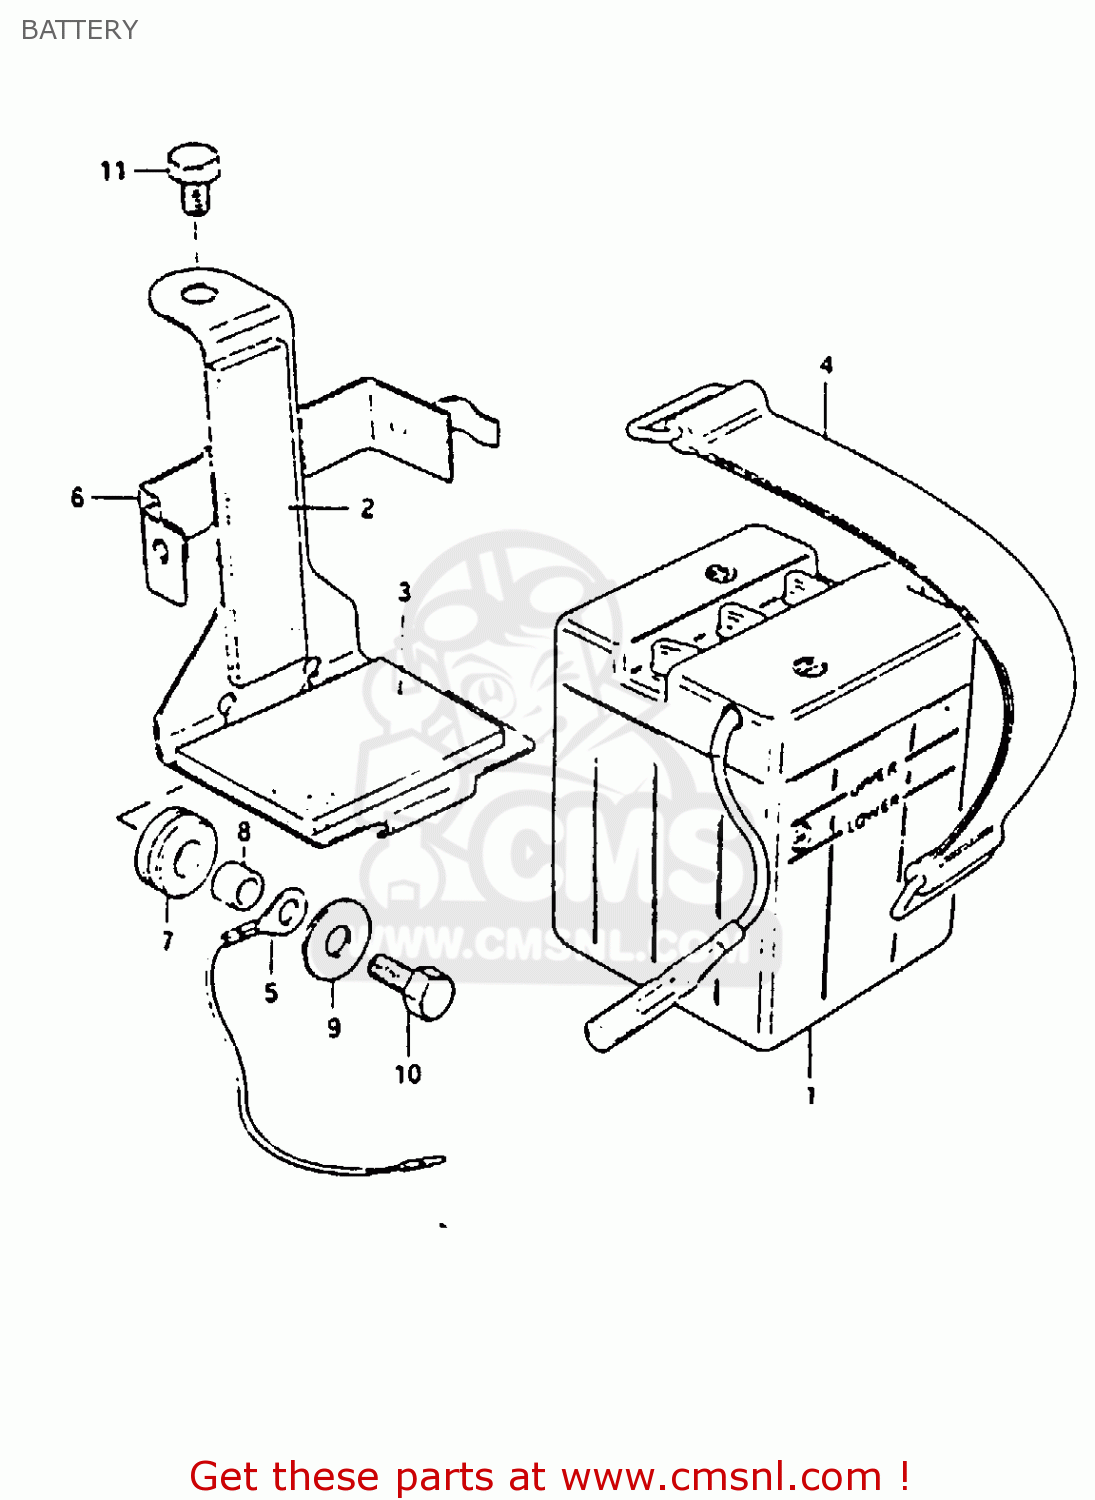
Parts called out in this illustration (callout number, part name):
1	BATTERY ASSY(6N4-2A4.2AH)
2	PROTECTOR
3	PROTECTOR,BATTERY
4	BAND
5	LEAD WIRE
6	HOLDER,BATTERY
7	CUSHION
8	SPACER(6.1X9X7.5)
9	WASHER
10	BOLT
11	BOLT
